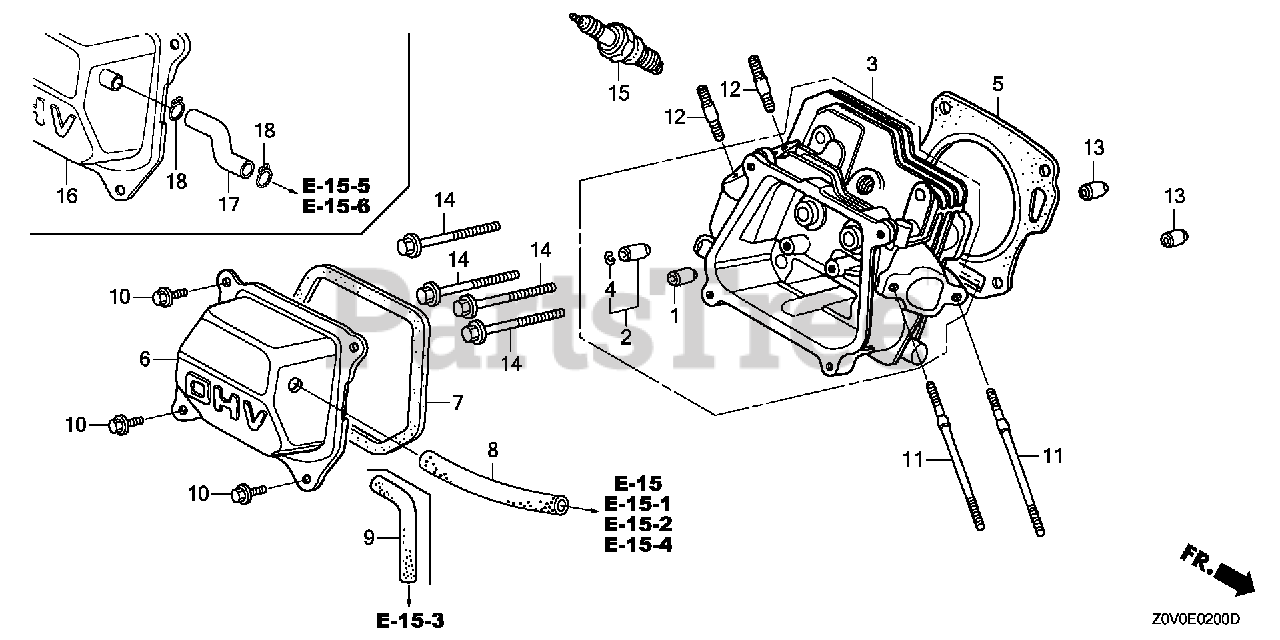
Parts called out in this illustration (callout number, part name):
1	GUIDE, VALVE (OVER SIZE)
2	GUIDE, EX. VALVE (OVER SIZE)
3	CYLINDER HEAD
4	CLIP, VALVE GUIDE
5	GASKET, CYLINDER HEAD (NIPPON LEAKLESS)
6	COVER, HEAD
7	GASKET, HEAD COVER
8	TUBE, BREATHER
10	BOLT, FLANGE (6X12) (CT200)
11	BOLT, STUD (6X112)
12	BOLT, STUD (8X32)
13	PIN, DOWEL (10X16)
14	BOLT, FLANGE (8X60)
15	SPARK PLUG (BPR5ES) (NGK)
15	SPARK PLUG (BPR6ES) (NGK)
